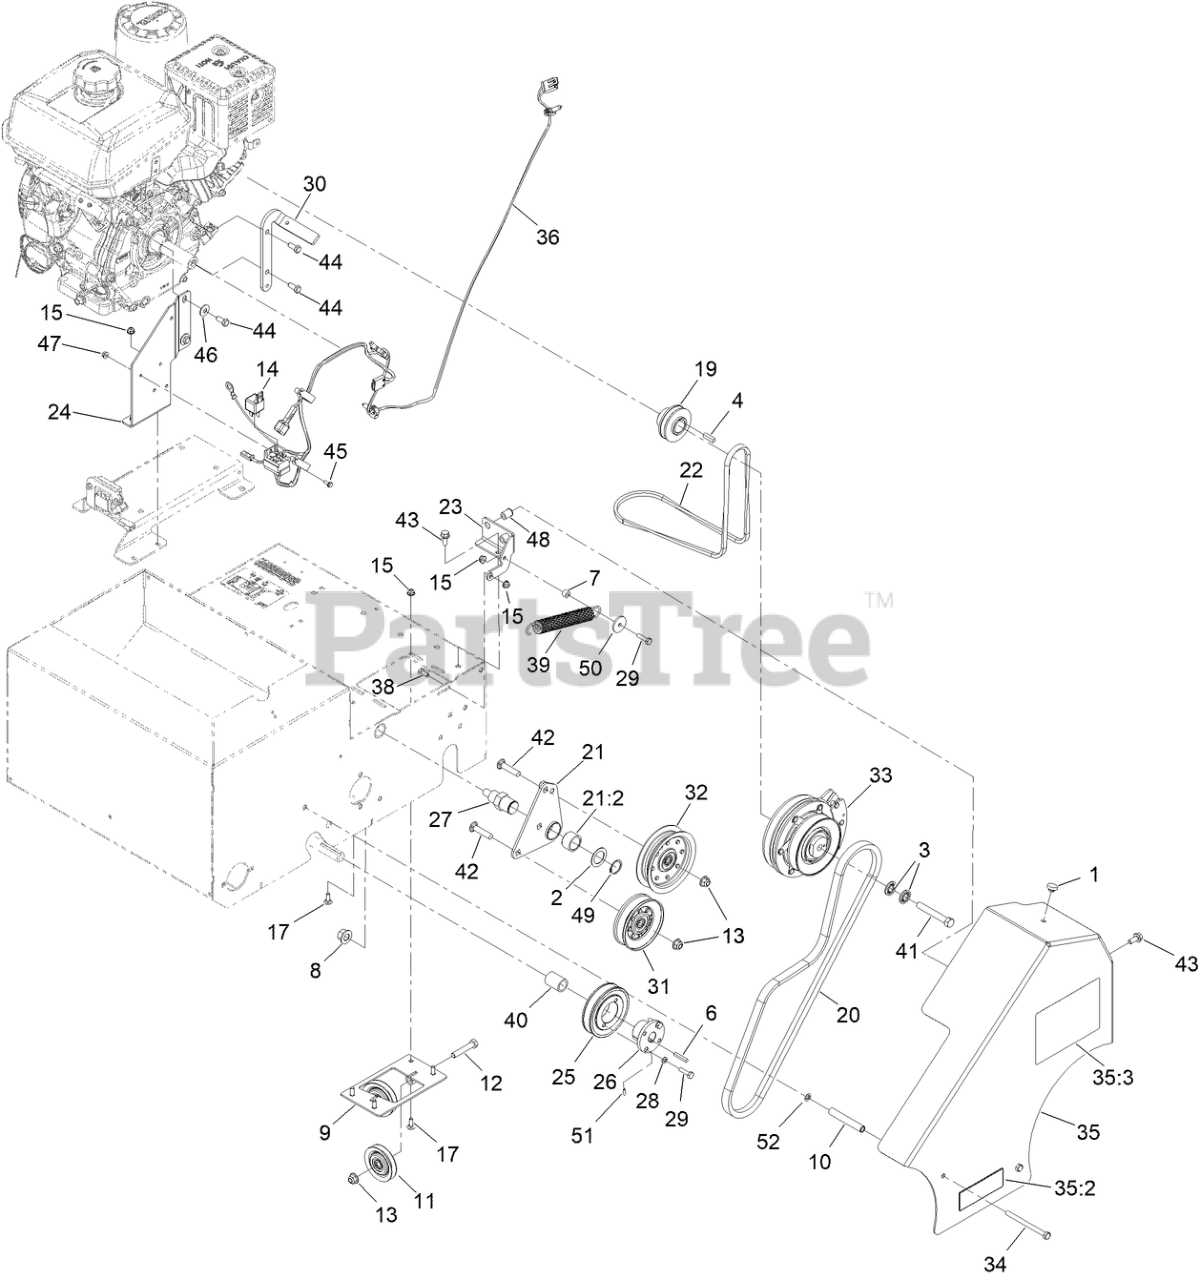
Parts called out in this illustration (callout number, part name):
1	BUMPER
2	WASHER-SPACER
3	WASHER-SPRING
6	KEY-SQUARE
7	SPACER
8	NUT-LOCK
9	PULLEY-TENSION
10	SPACER-KICKSTAND, LONG
11	PULLEY-IDLER
12	SCREW-HH
13	NUT-HF, NI
15	NUT-HF
17	BOLT-CARR
19	PULLEY-MULE DRIVE
20	BELT-SEEDER, CLUTCH
21	IDLER ARM ASM
21:2	BUSHING
22	BELT-MULE DRIVE
23	BRACKET-SPRING
24	GUARD-BELT
25	SHEAVE-TAPER LOCK
26	BUSHING-TAPER LOCK
27	PIVOT-IDLER
28	WASHER-LOCK
29	SCREW-HH
30	STOP-CLUTCH
31	PULLEY-IDLER V
32	PULLEY-IDLER FLAT (4.06-INCH)
33	CLUTCH-ELECTRIC
34	SCREW-HH
35	GUARD-BELT, W/DECALS
35:2	DECAL-DANGER
35:3	DECAL-GRAPH, SEED
36	HARNESS-WIRE
38	SCREW-HH
39	SPRING-EXTENSION
40	SPACER
41	SCREW-HH
42	SCREW-CARR
43	SCREW-HHF
44	SCREW-HH
45	SCREW-HWH
46	WASHER-BELLEVILLE
47	NUT-LOCK, FLANGE
48	NUT-CLINCH
49	RING-RETAINING
50	WASHER
51	SCREW-SET, HS
52	RING-RETAINING, BOLT
